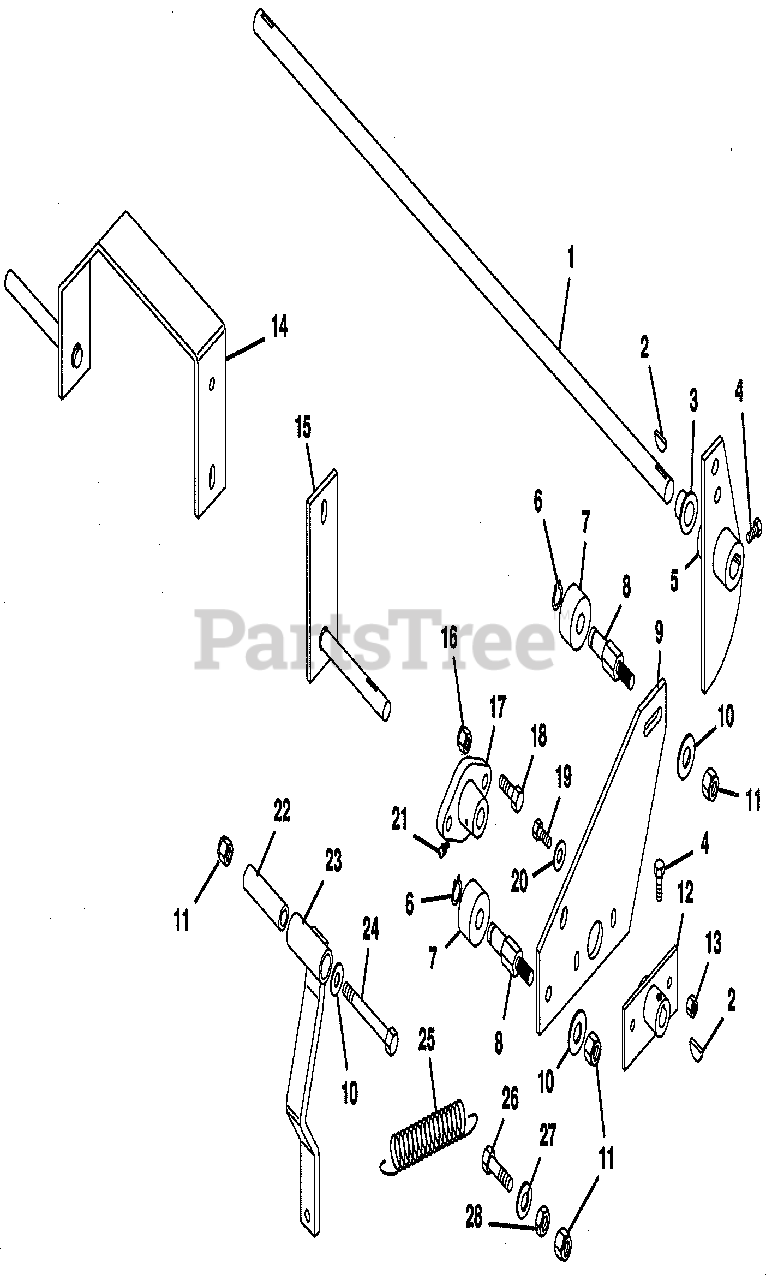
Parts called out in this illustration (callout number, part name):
1	SHAFT, SPEED CONTROL CAM
2	KEY, WOODRUFF .125 X .75
3	BUSH., FLG. .630 X 4.00 X .625 NY
4	BOLT, HEX 1/4-20 X .50
5	WELDMENT, CONTROL CAM
6	RING, RETAINING .500 SHAFT
7	ROLLER, NYLON
8	PIN, ROLLER
9	ARM, SPEED CONTROL
10	WASHER, FLAT .406 X .812 X .065
11	NUT, LOCK 3/8-16
12	WELDMENT, NEUTRAL ADJ.
13	NUT, LOCK 1/4-20
14	WELDMENT, PUMP CONTROL R.H.
15	WELDMENT, PUMP CONTROL L.H.
16	NUT, LOCK 5/16-18
17	BUSHING, FLANGED SUPPORT
18	BOLT, HEX 5/16-18 X 1.00
19	BOLT, HEX 1/4-20 X .750
20	WASHER, FLAT .281 X .625 X .065
21	FITTING, LUBE 1/4-28
22	BUSH., ST. .385 X .610 X 1.80 STL.
23	WELDMENT, DETENT STRAP
24	BOLT, HEX 3/8-16 X 2.75
25	SPRING, EXT. LE-063F-5
26	BOLT, HEX 3/8-16 X 1.50
27	WASHER, LOCK 3/8 REG.
28	NUT, HEX 3/8-16
